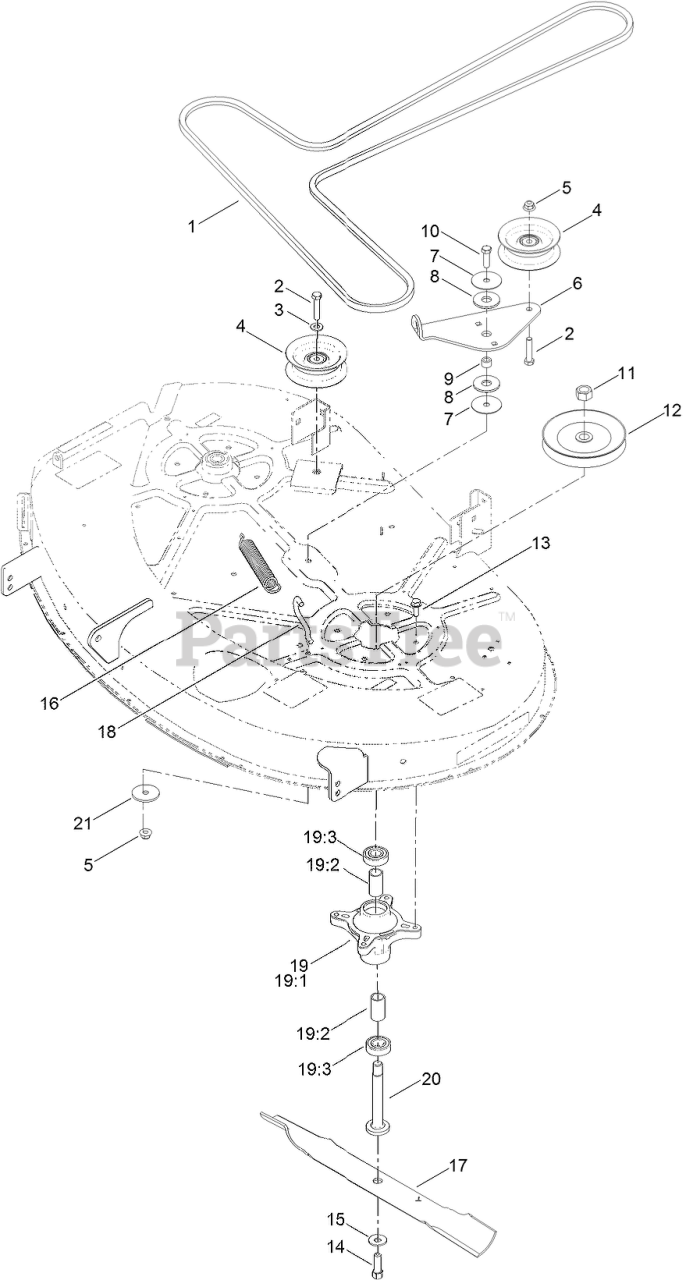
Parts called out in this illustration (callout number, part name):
1	V-BELT
2	SCREW-HH
3	WASHER-FLAT
4	PULLEY-IDLER, FLAT
5	NUT-HF, NI
6	ARM-IDLER
7	WASHER
8	WASHER-FRICTION, COMPOSITE
9	SPACER
10	SCREW-HH
11	NUT-HEX
12	Pulley
13	SCREW-TAPTITE
14	SCREW-HH
15	WASHER-BELLEVILLE
16	SPRING-EXTENSION
17	BLADE-HIGH LIFT
18	HOOK-RETURN, SPRING
19	SPINDLE ASM
19:1	SPINDLE
19:2	SPACER
19:3	BEARING-BALL
20	SHAFT-SPINDLE
21	WASHER-REBOUND
